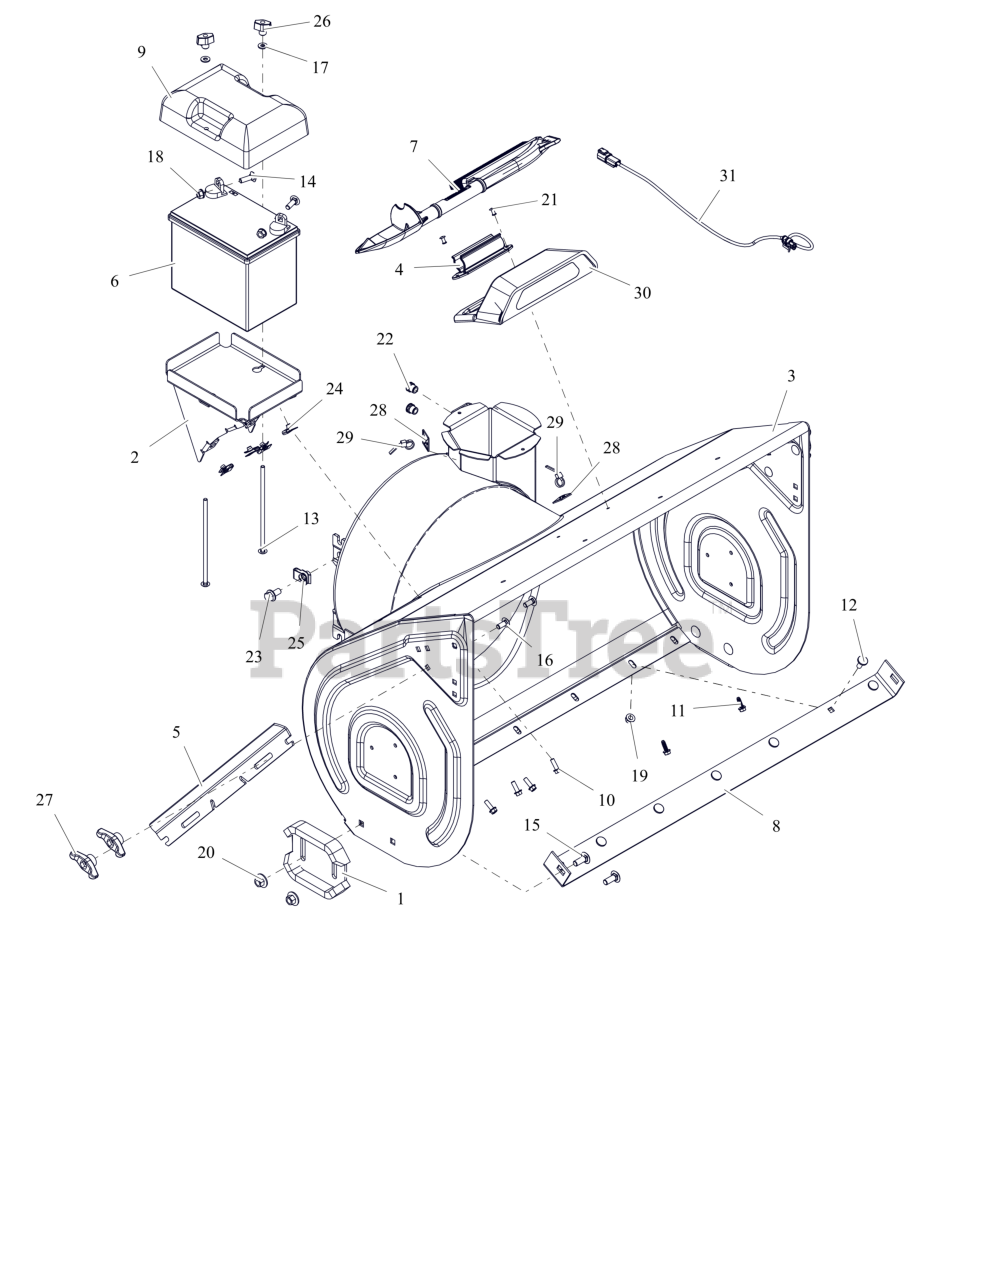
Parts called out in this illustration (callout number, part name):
1	RUNNER, SKID SHOE
2	TRAY, BATTERY
3	HOUSING, BLOWER 32" W/DECAL
4	MOUNT, SNOW CLEAN OUT
5	CUTTER, DRIFT
7	DEVICE, SNOW CLEAN OUT W/BRUSH
8	BLADE, SCRAPER-32"
9	COVER, BATTERY
10	BLT, HWH .25-20X.75 G5 ZCC
11	SCR, PLASTITE .25-10X.75 ZCC
12	BOLT, MODIFIED HEAD CARRIAGE
13	BLT,RHSN .25-20X7.00 G2 ZCC
14	BLT,RHSN .31-18X1.00 G5 ZCC
15	BLT,RHSSN .38-16X1.00 G5 ZCC
16	BLT, RHSSN.31-18X.750 G5 ZCC
17	WSHR,FLT .281X.625X.065 ZCC
18	NUT,LK-CTR-FLG .31-18 GF ZCC
19	NUT-LK-TOP-FLG .312-18 GF ZCC
20	NUT- CON-LN .375-16 ZC120
21	RIVET, #66 STEEL POP PD BLACK
22	NUT,THD,INSERT .38-16 ZC120
24	NUT-RTNR .25-20X.56
25	NUT-RTNR .375-16X.37
26	KNOB, WING - .25-20 UNC
27	KNOB,WING .31-18 UNC NYL/TALC
28	MOUNT, CABLE-TIE DOWN
29	CABLE TIE LG 5-1/2
30	HOUSING, LIGHT - LED
31	HARNESS- WIRE - LIGHT JUMPER
